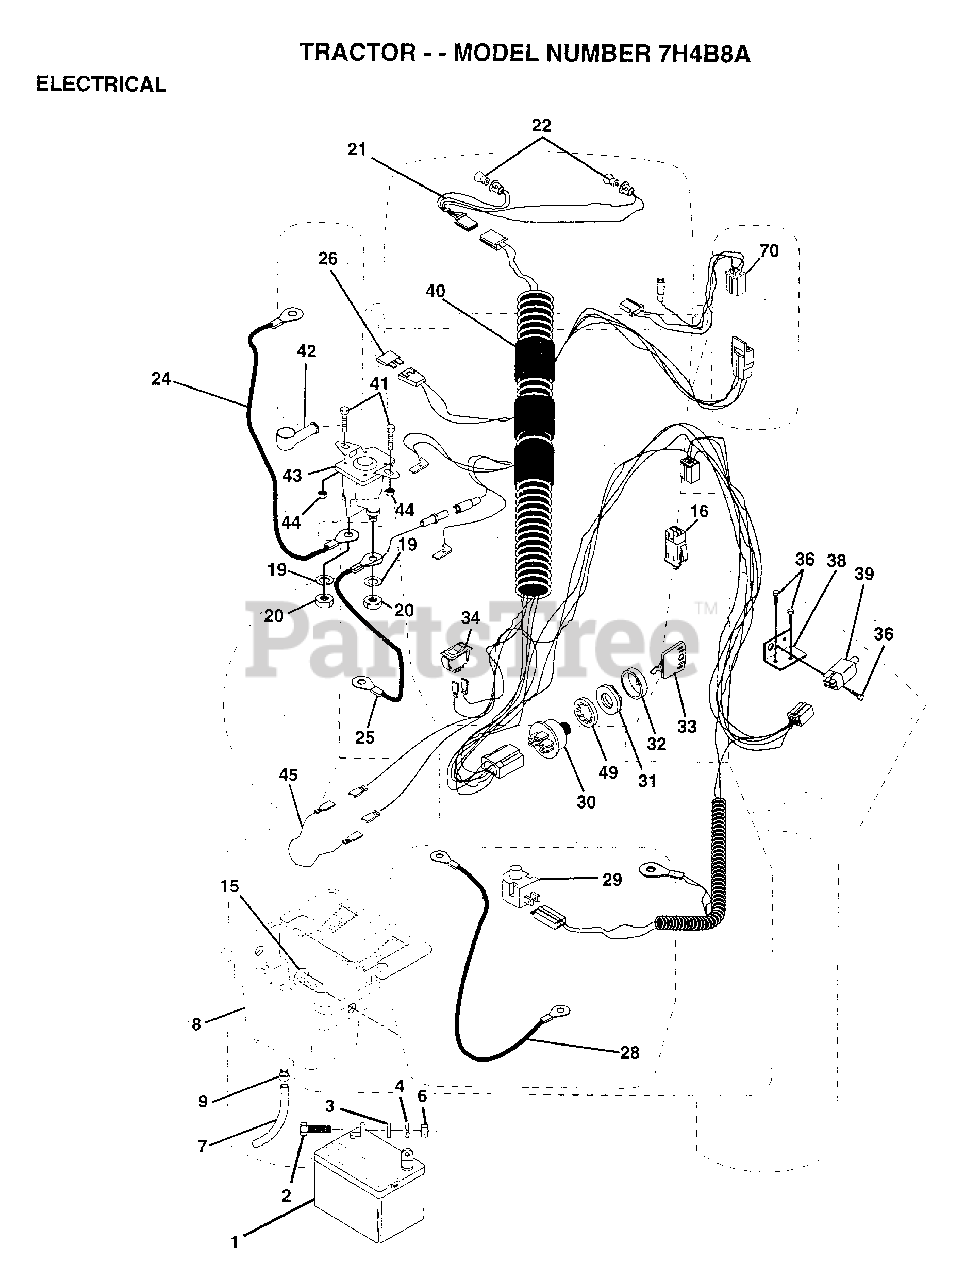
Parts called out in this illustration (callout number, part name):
2	BOLT LT
3	WASHER
4	LOCKWASHER
7	TUBE T
9	HOSE CLAMP T
15	FASTNER.SNAP-IN
16	SWITCH INTERLOCK
20	NUT
21	"HARNESS,LIGHT SOC"
22	HEADLAMP BULB
24	"CABLE T, BATTERY"
25	CABLE.BTRY.6GA.RD
26	FUSE HYT
28	CABLE T
29	SWITCH SEAT
32	COVER KEY SWITCH
33	KEY MLD GEN DELTA
34	SWITCH LT
36	SCREW
38	BRACKET SWITCH IN
39	SWITCH INTERLOCKT
40	HARNESS.IGN.DASH.
41	BOLT HXHD FIN
44	NUT HXKEP 1/4X20
45	ADAPTER AMMETER
49	WASHER PINNED
70	HARNESS ENG DUAL
